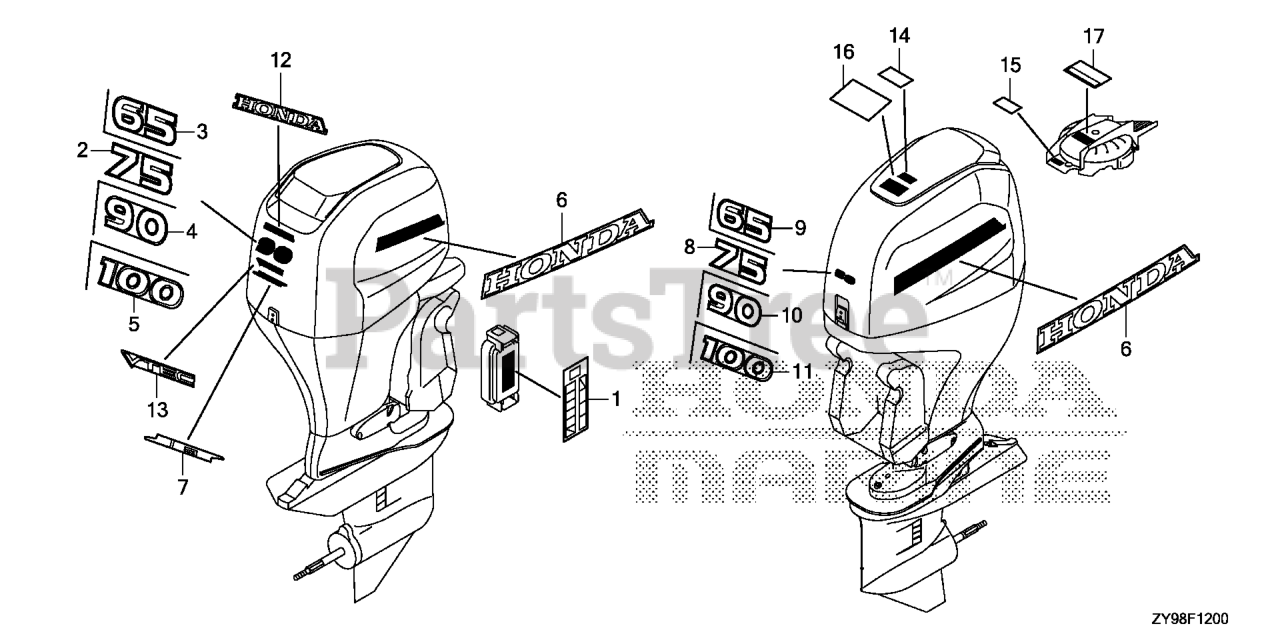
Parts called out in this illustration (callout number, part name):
1	LABEL, FUSE
2	MARK, RR. (75)
6	MARK, SIDE STRIPE
8	MARK, FR. EMBLEM (75)
12	MARK, HONDA
15	LABEL, OIL CAUTION (ENGLISH)
16	LABEL, CAUTION OPERATOR (ENGLISH)
17	MARK, EMERGENCY START (ENGLISH)
